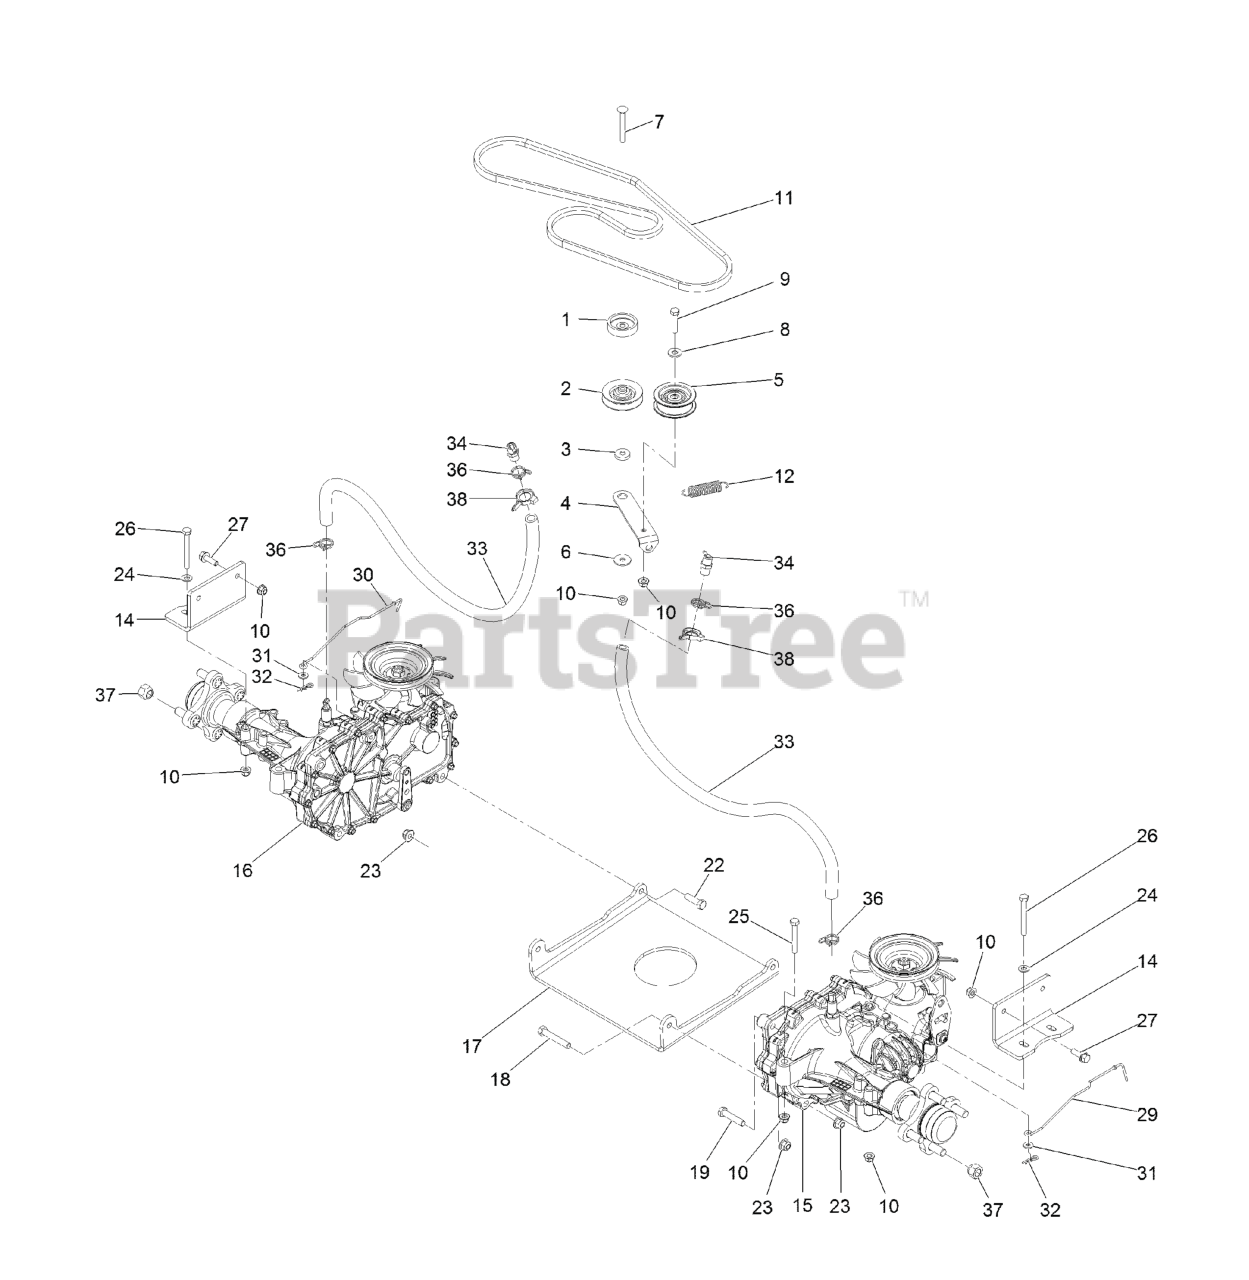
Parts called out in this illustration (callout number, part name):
2	PULLEY-IDLER
3	SPACER-ARM, IDLER
4	Arm-Idler
5	Pulley-Idler, Flat
6	WASHER-PIVOT
7	SCREW-CARR
8	WASHER-FLAT
9	SCREW-HH
10	NUT-HF, NI
11	V-BELT
12	Spring-Return, Pedal
14	MOUNT-HYDRO
15	LH HYDRO TRANSMISSION ASM
16	RH HYDRO TRANSMISSION ASM
17	PLATE-CROSS, HYDRO
18	SCREW-HH
19	SCREW-HH
22	SCREW-HH
23	NUT-HF, NI
24	WASHER-PLAIN
25	SCREW-HH
26	SCREW-HH
27	SCREW-HHF
29	ROD-BYPASS, LH
30	ROD-BYPASS, RH
33	HOSE-HYDRO
34	BREATHER KIT
36	CLAMP-HOSE
37	NUT-LUG
38	CLAMP-HOSE
